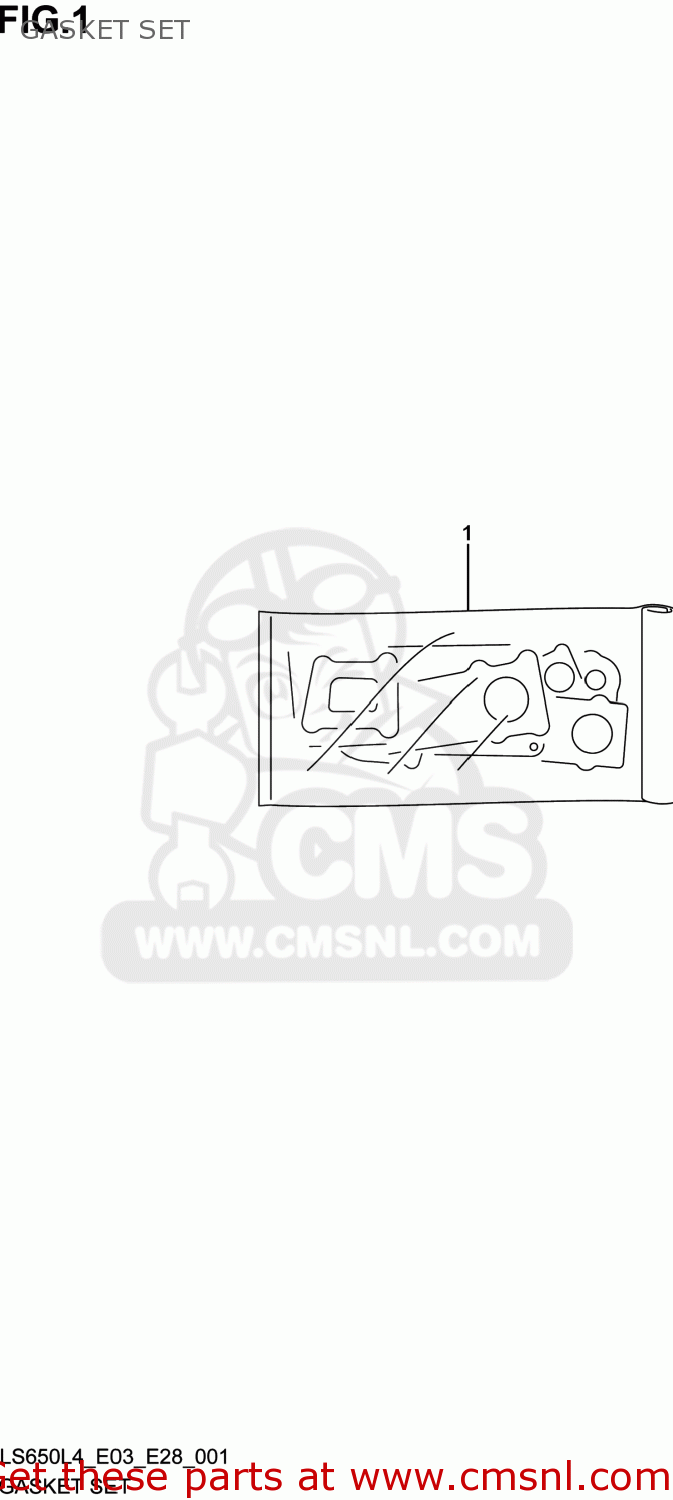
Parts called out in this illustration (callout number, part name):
1	GASKET SET (NAS)
2	GASKET,CYLINDER HEAD (NAS)
3	O RING,CYL HEAD COVER
4	GASKET,CYLINDER (NAS)
5	GASKET,CLUTCH COVER (NAS)
6	GASKET,GENERATOR COVER (NAS)
7	GASKET,GEAR SHIFT COVER (NAS)
8	GASKET,EXHAUST PIPE (NAS)
9	GASKET(5.8X13X1.2) (NAS)
10	GASKET(10.2X20X2).3 (NAS)
11	O RING(D:1.9,ID:6.8)
12	O RING(D:1.9,ID:8.6)
13	O RING(D:2.4,ID:9.6)
14	O RING(D:2.4,ID:15.8)
15	O RING(D:3.1,ID:16.8)
16	O RING(D:2.4,ID:23.7)
17	O RING(D:3.1,ID:32.7)
18	O RING(D:2.4,ID:45.7)
19	O RING(D:2.4,ID:23)
20	O RING(D:2.4,ID:73)
